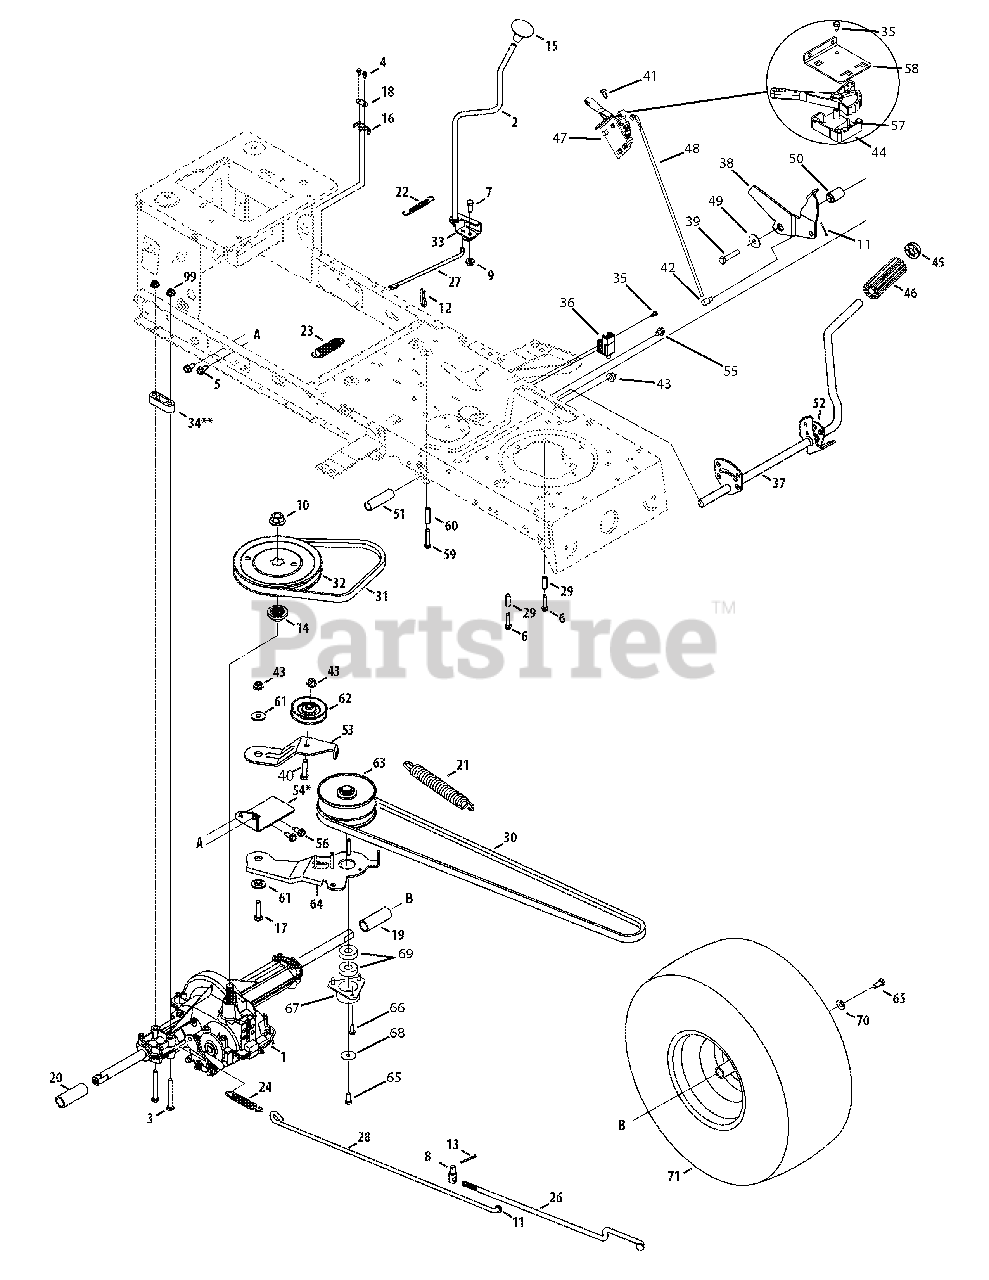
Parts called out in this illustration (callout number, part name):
1	Transmission
2	Lever Assembly, Shift
3	Screw, 5/16-18, 2.75
4	Screw, #8-18, 0.500
5	Screw, 5/16-18, 0.750
6	Screw, 1/4-20, 1.250
7	Screw, 5/16-18, .75, Gr5
8	Ferrule, 3/8-24 x .375 Dia.
9	Nut, Flange Lock, 5/16-18, GrF
10	Nut, Flange, 9/16-18, Gr2
11	Pin, Cotter, 3/32, 1.0
12	Cotter Pin, Internal .125 Dia
13	Pin, Cotter, 1/8 x 1.25
14	Hub, Pulley, 5/8 Spline
15	Knob, Shift
16	Spring Switch, Short
17	Screw, 3/8-16 x 1.50
18	Plate, Insulator Nut
19	Sleeve, .758 x .821 x 3.3125
20	Sleeve, .758 x .821 x 2.4375
21	Spring, Extension, 1.15 OD x 7.90
22	Spring, Extension
23	Spring, Extension, .80 OD x 3.28
24	Spring, Extension, .59 OD x 4.00
25	Washer, Flat, .330 x .630 x .0635
26	Variable Speed Control Rod
27	Rod, Shift
28	Rod, Brake
29	Spacer, .260 x .372 x 1.030
30	Belt
31	Belt
32	Pulley, V-Type, 7.25 Dia
33	Shift Bracket, Adjustable
34	Spacer .68
35	Screw, #10, 0.500
36	Switch, Interlock
39	Screw, 3/8-16, 2.00, Gr5
40	Screw, 3/8-16 x 1.75
41	Screw, 1/4-20, 0.500
42	Adjustment Ferrule 1/4-20
43	Nut, Flange Lock, 3/8-16, GrF
44	Control Cover
45	Push Cap, 5/8
46	Pad, Foot, 4.0
47	Shift Cont. Assembly, 6-Spd
47	Shift Cont. Assembly, 7-Spd
48	Control Rod, Speed Selector
49	Washer, Flat, .411 x 1.25 x .100
50	Spacer, Flge, .390 x .671 x 1.095
51	Spacer, .640 ID x .76 OD x 2.63
52	Support Bracket, Pedal
53	Bracket, Idler
54	Torque Bracket, Transmission
55	Screw, 5/16-18, 0.625
56	Screw, 5/16-18, 0.750
57	Shift Lever Spring
58	Control Bracket
59	Screw, 1/4-20 x 1.625
60	Spacer, .260 x .372 x 1.420
61	Spacer, Shoulder, .625 ID x .169
62	Pulley, V Idler A x 3.06
63	Pulley Ass’y, Variable Speed
64	Bracket Ass’y, Variable Speed
65	Screw, 5/16-24, .750, Gr5
66	Screw, 1/4-20, 1.50
67	Cup, Bearing
68	Washer, Flat, .330 x 1.25 x .06
69	Bearing, Ball, 17 x 40 x 12
70	Bell Washer, .34 x .872 x .060
71	Rim Assy.
72	Screw, 1/4-20 x .500
